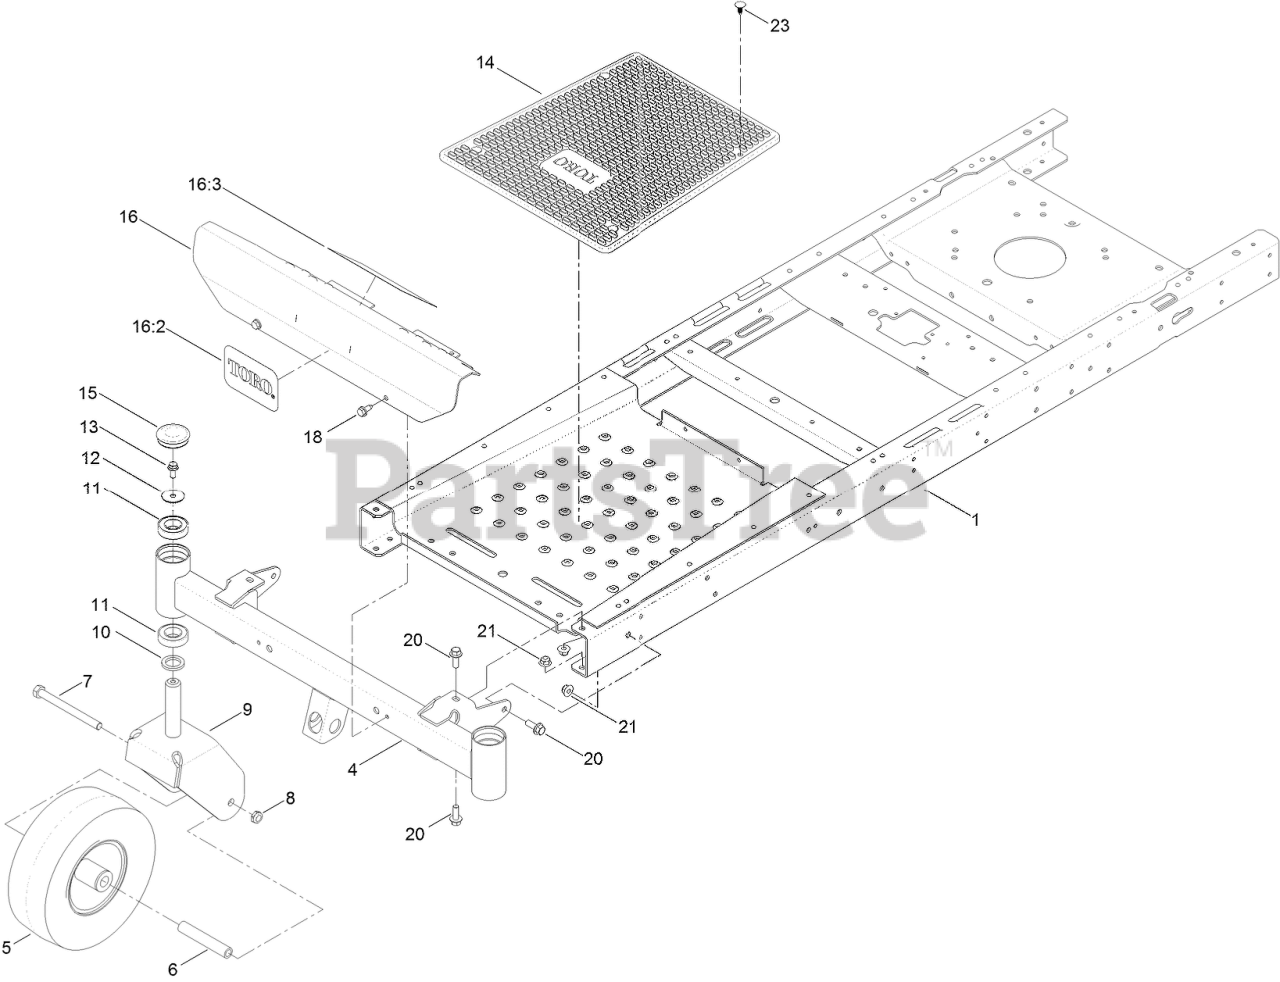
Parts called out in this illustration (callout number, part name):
1	FRAME ASM
4	AXLE-FRONT, NARROW
5	Caster Wheel ASM
6	BUSHING-SPANNER
7	SCREW-HH
8	NUT-LOCK, NI
9	CASTER FORK ASM
10	WASHER-THRUST
11	BEARING-BALL
12	WASHER-FLAT
13	SCREW-HHF
14	MAT-FLOOR
15	CAP-GREASE
16	FOOTREST ASM
16:3	DECAL-DANGER
18	SCREW-HWHTF
20	SCREW-HHF
21	NUT-HF, NI
23	PLUG-PLASTIC
